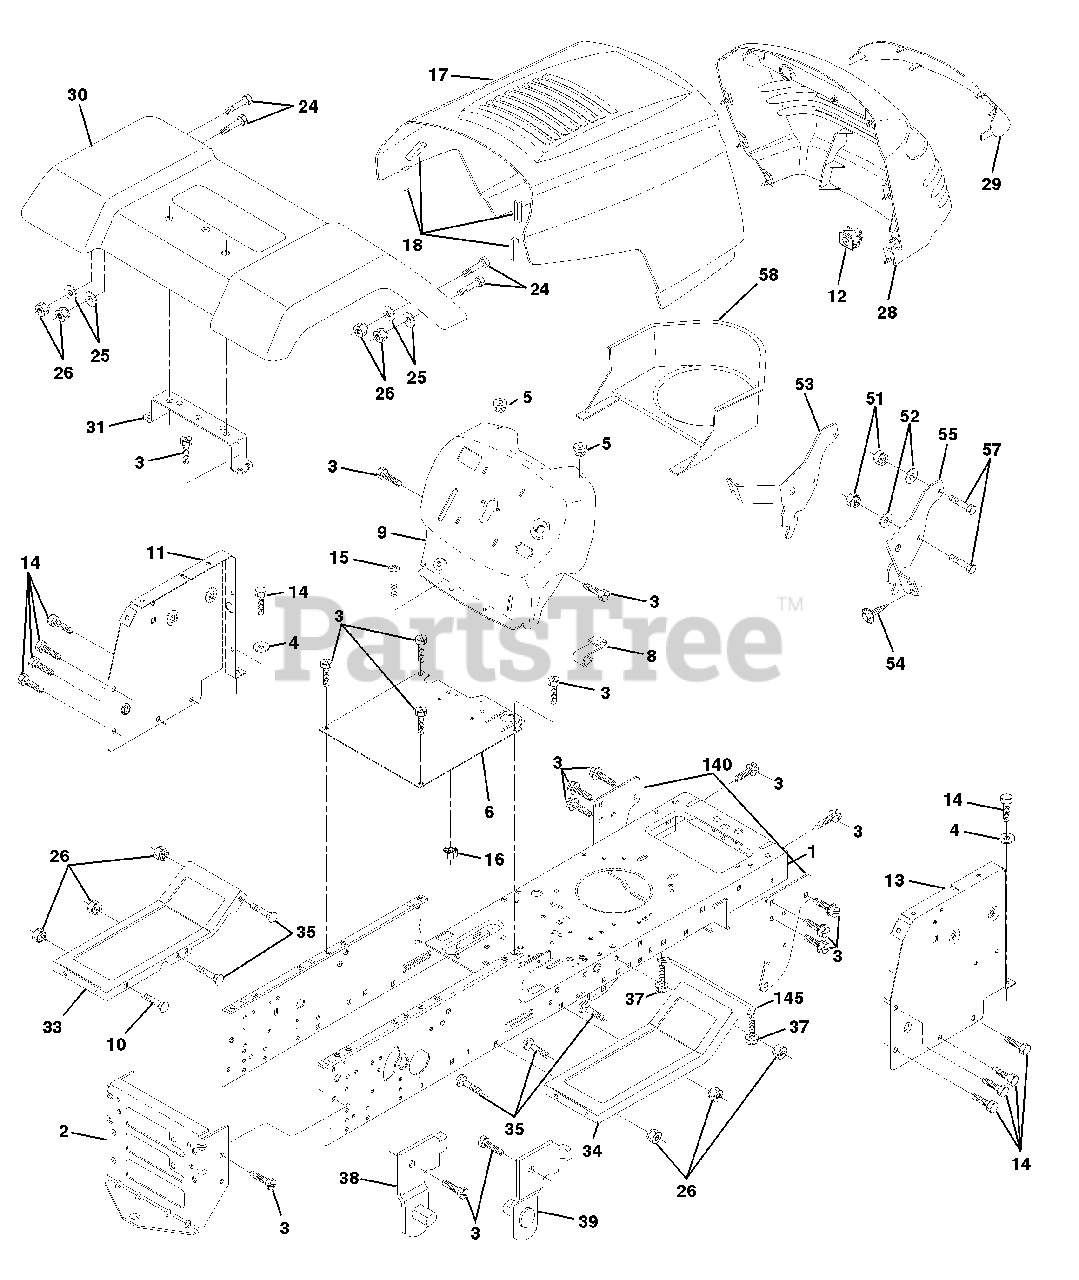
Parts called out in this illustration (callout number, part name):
1	Chassis Lt Stamping 98
2	Drawbar, Stretch
3	Screw Thdrol 3/8-16x3/4 Ty-tt
4	Washer 13/32 X 3/4 X 16 Ga.
5	Bumper, Hood/Dash
6	Saddle Silkscreen Flt Sdl
8	Clip Retainer Slide-On
9	Dash Slkscr
10	Bolt, Carriage 3/8-16 x 1
11	Panel Dash LH
12	Clip Tinnerman Grille P.L
13	Panel Slkscr Dash RH
14	Screw Thdrol 3/8-16x1/2 Ty-tt
15	Screw Mach TRHD 5/16-18uncx3/4
16	Nut Keps 5/16-18 Unc
17	Hood Pnt Stl Prvt Lbl
18	Bumper Hood
24	Bolt Fin Hex 3/8-16unc X 1 Gr. 5
25	Washer 13/32 X 13/16 X 12 Ga
26	Nut Lock Hex w/Ins 3/8-16 Unc
28	Grille P.L Ms 428
29	Lens Grille Private Label
30	Fender Pnt LT W/o Shift(red)
31	Bracket Fender Repl 109873x
33	Footrest Pnt LH Perf
34	Footrest Pnt RH Perf
35	Bolt Rdhd Sht Sqnk 3/8-16 X3/4
37	Screw Thdrol 5/16-18 x 1/2 TYT
38	Bracket Asm Pvt LH MWR Rear
39	Bracket Asm Pvt RH MWR Rear
51	Nut Lock W/Insert 1/4-20unc
52	Washer 9/32 x 7/8 x 16 Ga.
53	Bracket Grille Lh
54	Screw Lock Spider #8 x 7/8
55	Bracket Grille Rh
57	Bolt Fin Hex 1/4-20 unc x .75
58	Duct Air Engine PL/LT
140	Bracket Suspension Front
145	Rod Pivot Chassis/Hood
